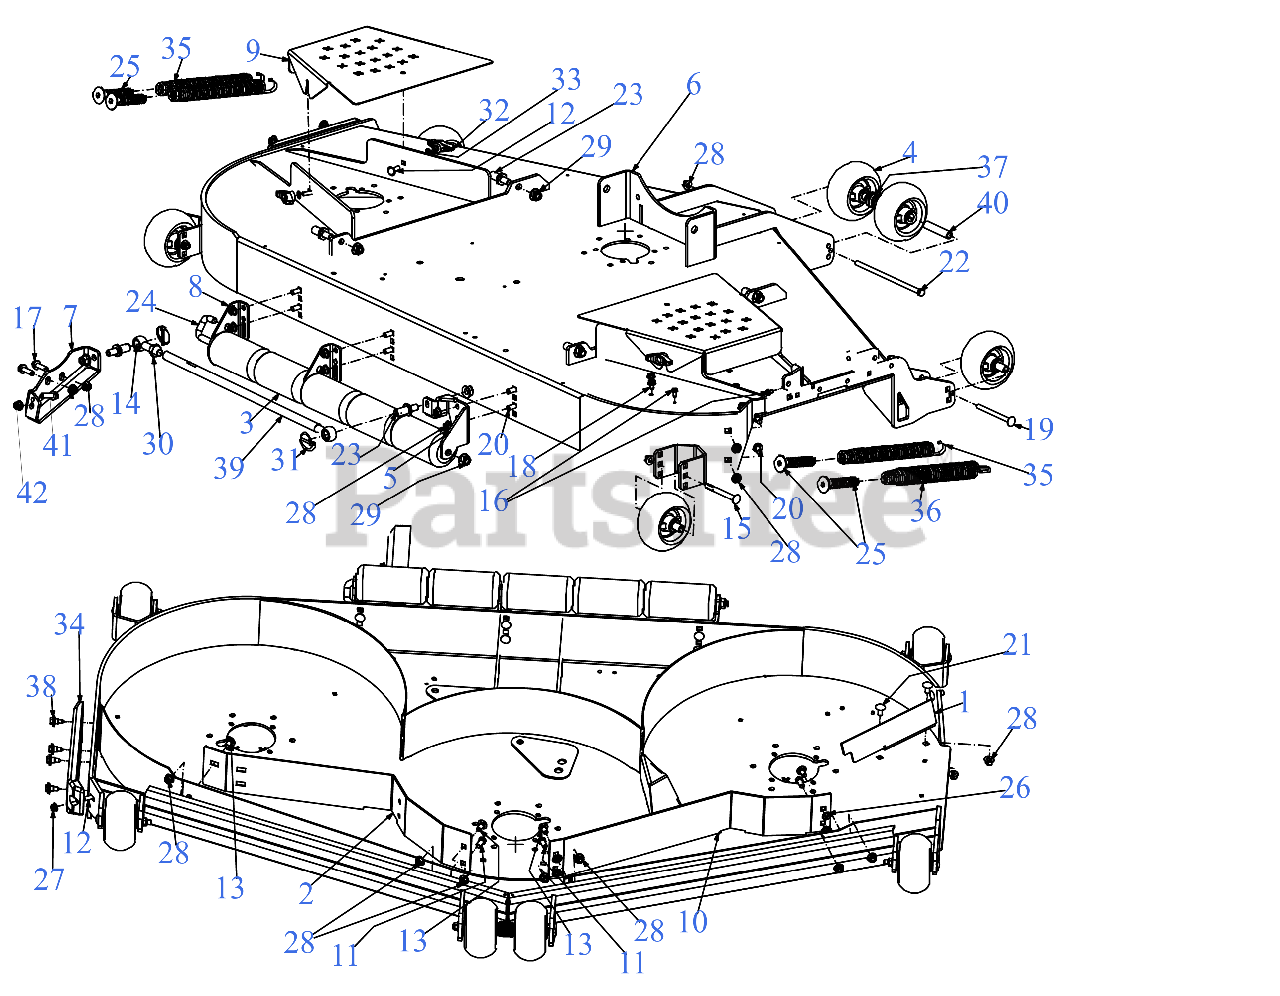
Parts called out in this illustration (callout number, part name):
1	BAFFLE - CHUTE
2	BAFFLE - 72" ADJ
3	ROLLER ASSEMBLY
4	5" DIA DECK WHEEL COMPLETE
4	WHEEL BUSHING
7	STABILIZER MOUNTING BRACKET
11	HEX SCREW 3/8-16 x .75
12	CARRIAGE BOLT 5/16-18 x 1.00
13	CARRIAGE BOLT 3/8-16 x .750 GR5
14	BOLT 5/8-16 x 2.63
15	CARRIAGE BOLT 3/8-16 x 4.00 GR5
16	SCREW 1/4-20 X.500
17	SCREW 3/8-16 x 1.25 GR5
18	SCREW 5/16-18 x .500
19	CARRIAGE BOLT 3/8-16 x 4.25 GR5
20	CARRIAGE BOLT 3/8-16 x 1.00 GR5
21	CARRIAGE BOLT 3/8-16 x .75
22	SCREW 3/8-16 x 8.5 GR5
24	REAR ROLLER PIN
25	SPRING INSERT SCREW
27	FLANGE LOCK NUT 5/16-18
30	HEX JAM NUT
31	LYNCH PIN .1875
32	WING KNOB 5/16-18
34	DECK SKID PLATE (LH)
35	EXTENTION SPRING 1.20 x 11.35
36	EXTENSION SPRING 1.44 OD x 11.36
37	FLAT WASHER
38	SHOULDER SCREW .43X.29X5/16-18 TT
40	WHEEL SPACER .38ID x 3.04LG
41	HEX HEAD BOLT (3/8-16:1.50 GR8)
42	LOCK NUT (3/8-16)
